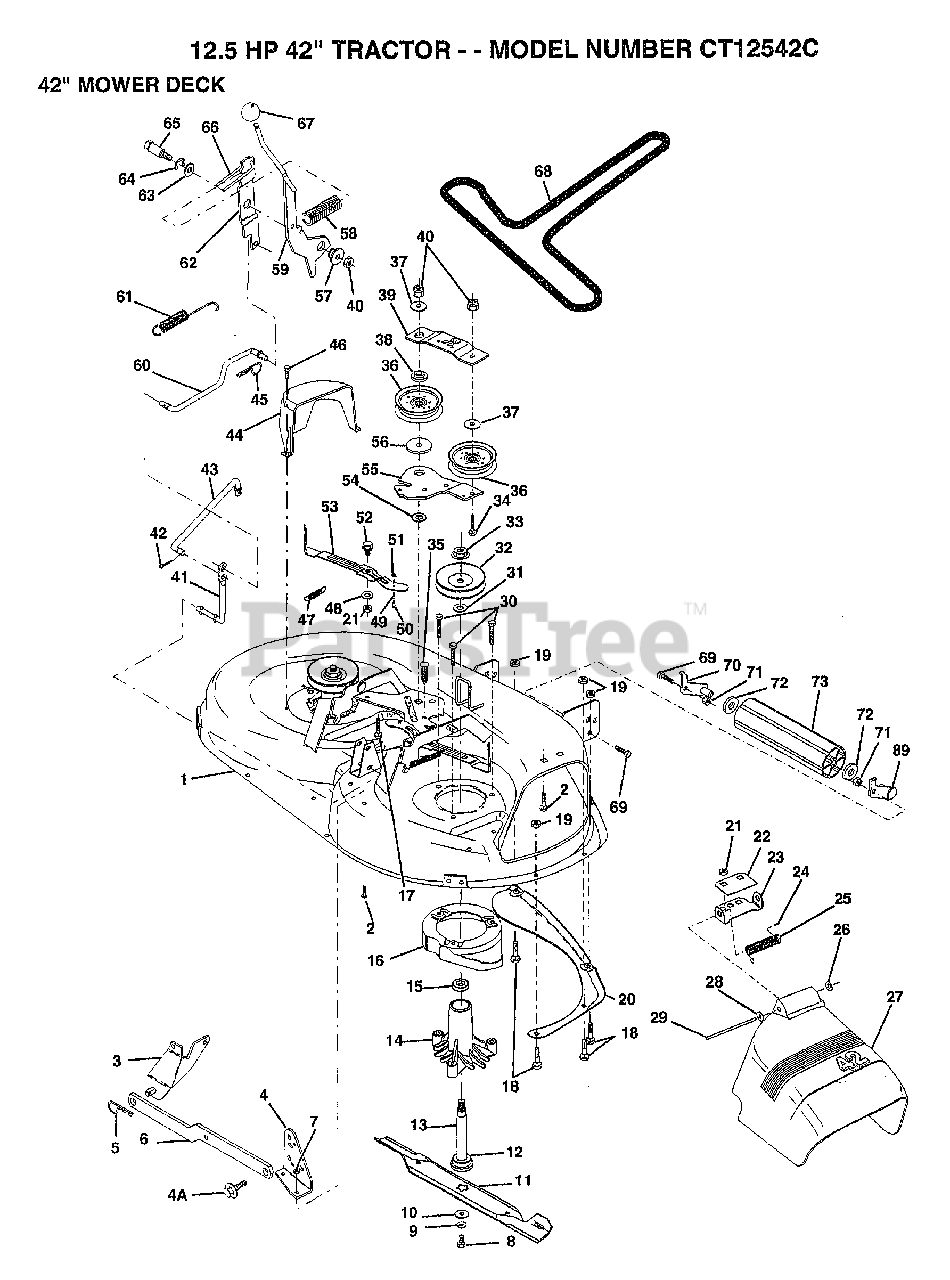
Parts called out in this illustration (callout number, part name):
2	BOLT
3	BRKT ASM SWAY BAR
4	BRKT DECK SW BAR
4A	BOLT SHD 5/16-18
7	NUT
8	BLADE BOLT
10	WASHER BLADE
11	"BLADE.42"" HIPERF"
12	BEARING.BALL
14	HSG ASM MANDREL
15	BEARING
17	BOLT CARRIAGE
18	BOLT
19	NUT
22	STIFFENER BRKT
23	DEFLECTOR BRKT
24	CAP-SLEEVE LT
25	SPRING TORSION
26	NUT PUSH M
27	DEFLECTOR.SHIELD
28	WASHER
29	HINGE ROD
31	WASHER
34	BOLT
35	XMAS TREE FASTNER
36	FLAT IDLER PULLEY
37	WASHER GT
38	RETAINER SPACER
39	IDLER ARM STIFF
41	PIVOT ROD
43	CLUTCH ROD SECOND
45	RETAINER M
46	SCREW LT
47	SPRING EXTENSION
48	HARD SMALL WASHER
50	SHOULDER BOLT
51	LOCKNUT
53	BRAKE PAD ARM ASM
54	HARDENED WASHER
55	IDLER ARM
56	SPACER RETAINER
57	BUSHING
59	CLUTCH ARM PRI AS
60	"ROD, CLUTCH PRIM"
61	RETURN SPRING
62	CLUTCH ARM SECOND
63	WASHER
64	RING
65	SHOULDER BOLT
66	SPRING KEEPER
68	BELT-V.92.4.MWR
69	BOLT
72	WASHER
